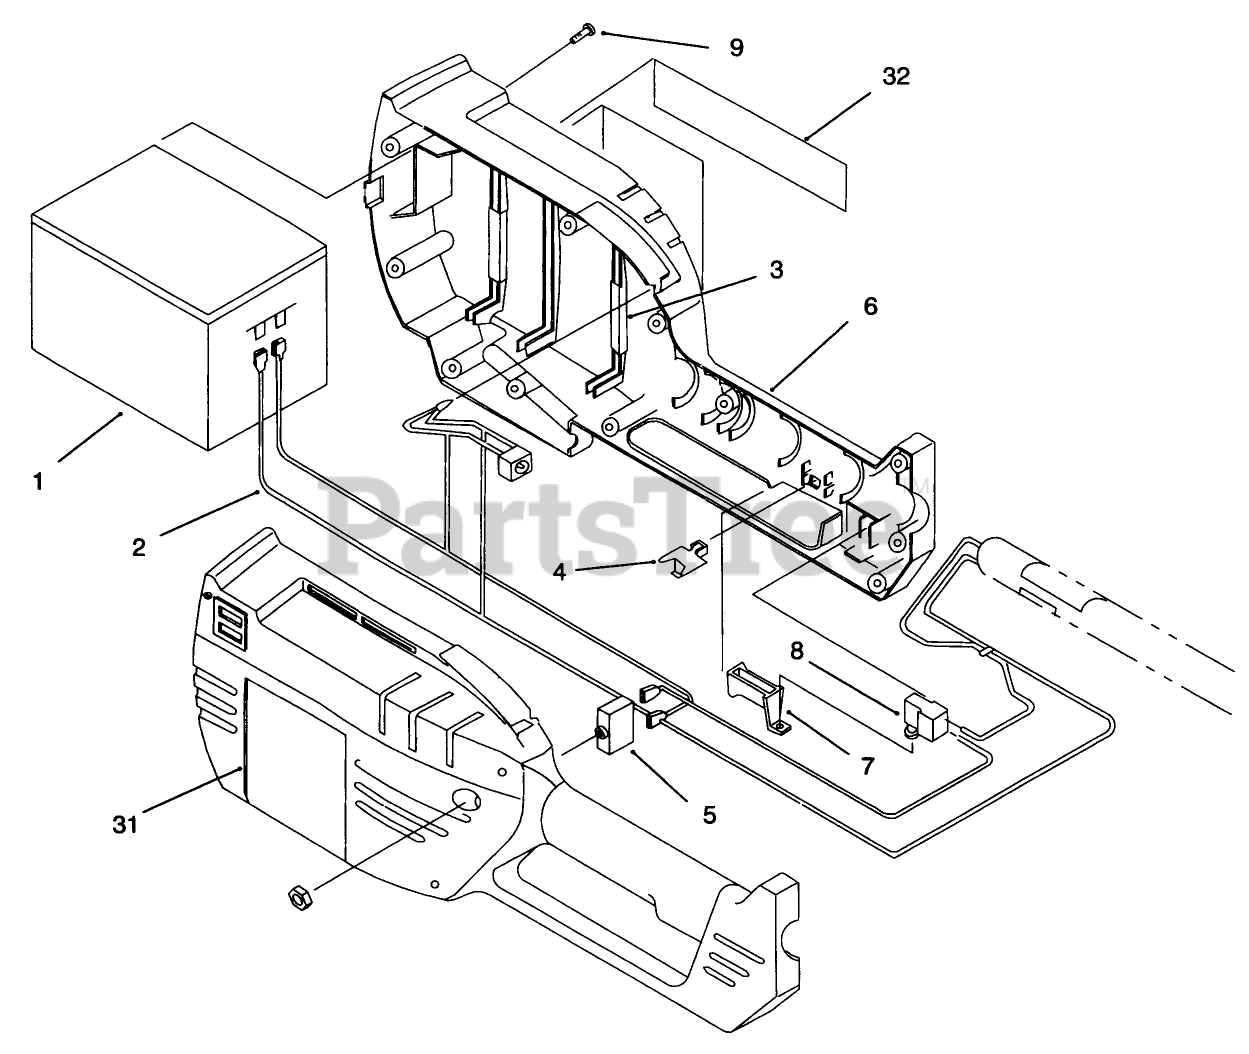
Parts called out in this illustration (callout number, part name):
1	Battery
2	ASM - WIRING HARNESS
3	CUSHION-BATTERY SET (5)
4	SWITCH - SAFETY RELEASE
5	SWITCH-THERMAL OVERLOAD
6	HSG - BATTERY W/O DECALS
7	Trigger
8	SWITCH
9	SCREW - HOUSING
31	DECAL - HOUSING TORO
32	DECAL - RECYCLE BATTERY
